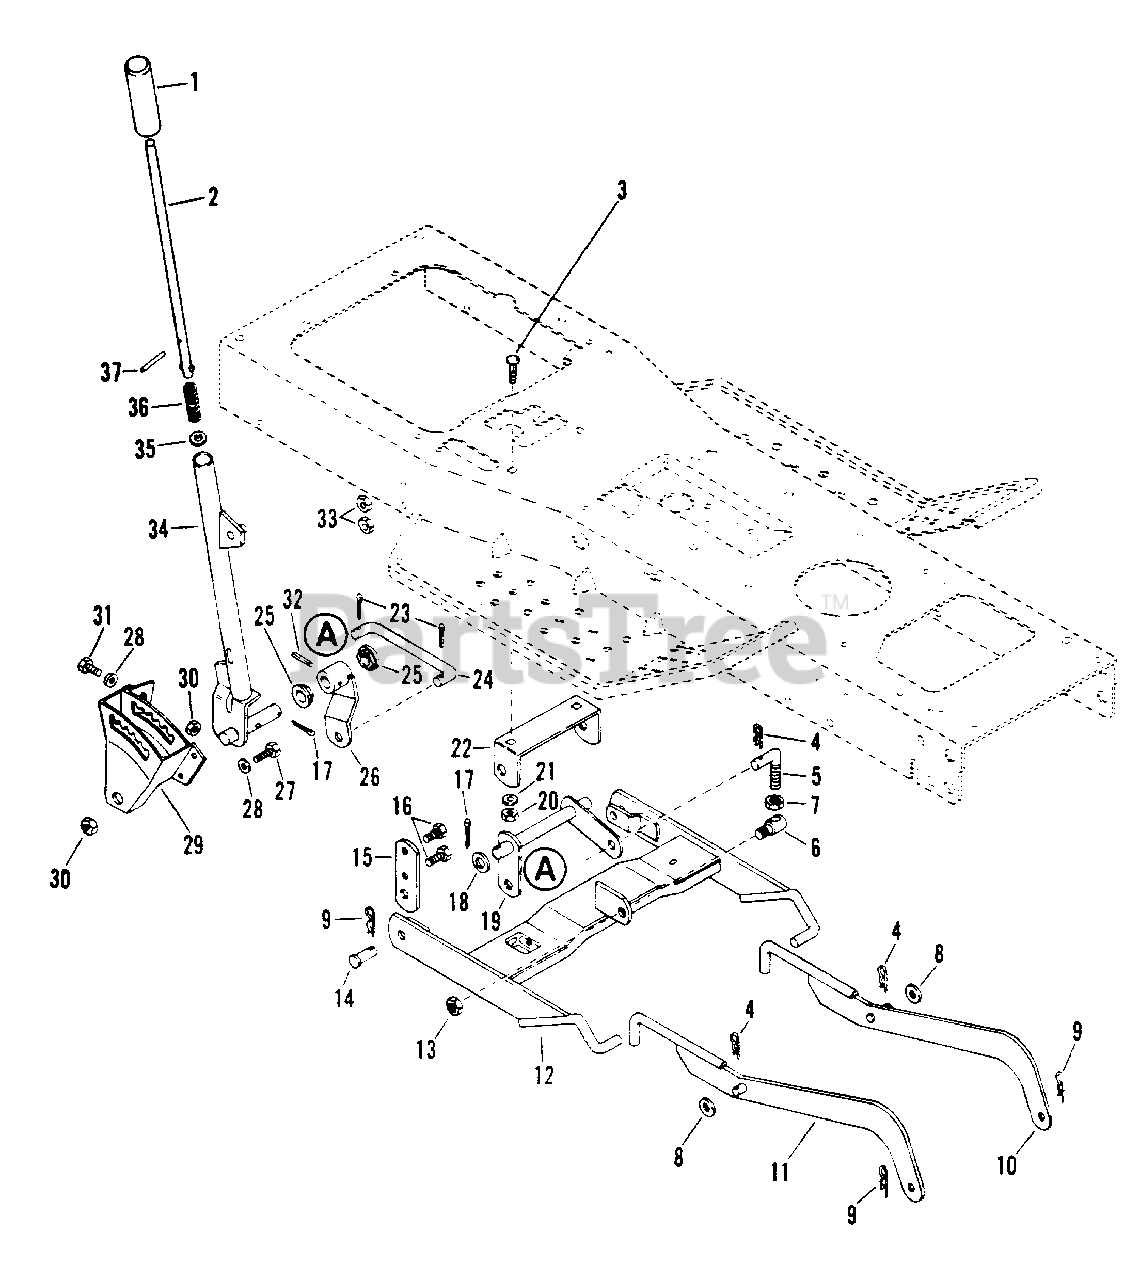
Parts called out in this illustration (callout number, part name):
1	GRIP
2	ROD, PLUNGER
3	BOLT, CARRIAGE 3/8-16X.75
4	HAIRPIN, INTERNAL
5	LINK, ADJUSTABLE
6	END, ROD
7	NUT, JAM 1/2-13 HEX
8	WASHER, FLAT .500X1.250X.083
9	HAIRPIN, INTERNAL
10	ARM, FRONT HANGER L.H.
11	HANGER, R.H.
12	HANGER, REAR
13	NUT, LOCK 1/2-13
14	PIN, CLEVIS
15	BRACKET, HANGER
16	BOLT, HEX 3/8-16X.75
17	PIN, COTTER .125X1.500
18	WASHER, FLAT .813X1.37X.100
19	LEVER, CENTER LIFT
20	NUT, HEX 3/8-16
21	WASHER, LOCK 3/8 REG.
22	BRACKET, CENTER LIFT
23	PIN, COTTER .125X1.00
24	LINK, LIFT
25	BUSHING, FLANGE
26	ARM, LIFT
27	BOLT, HEX 5/16-18X1.25
28	WASHER, FLAT .312X.734X.065
29	QUADRANT, LIFT
30	NUT, LOCK 5/16-18
31	BOLT, HEX 5/16-18X.75
32	PIN, GROOVE 1/4
33	NUT, LOCK 3/8-16
34	HANDLE, LIFT
35	WASHER, FLAT .469X.938X.065
36	SPRING
37	PIN, SPRING .250X1.750
